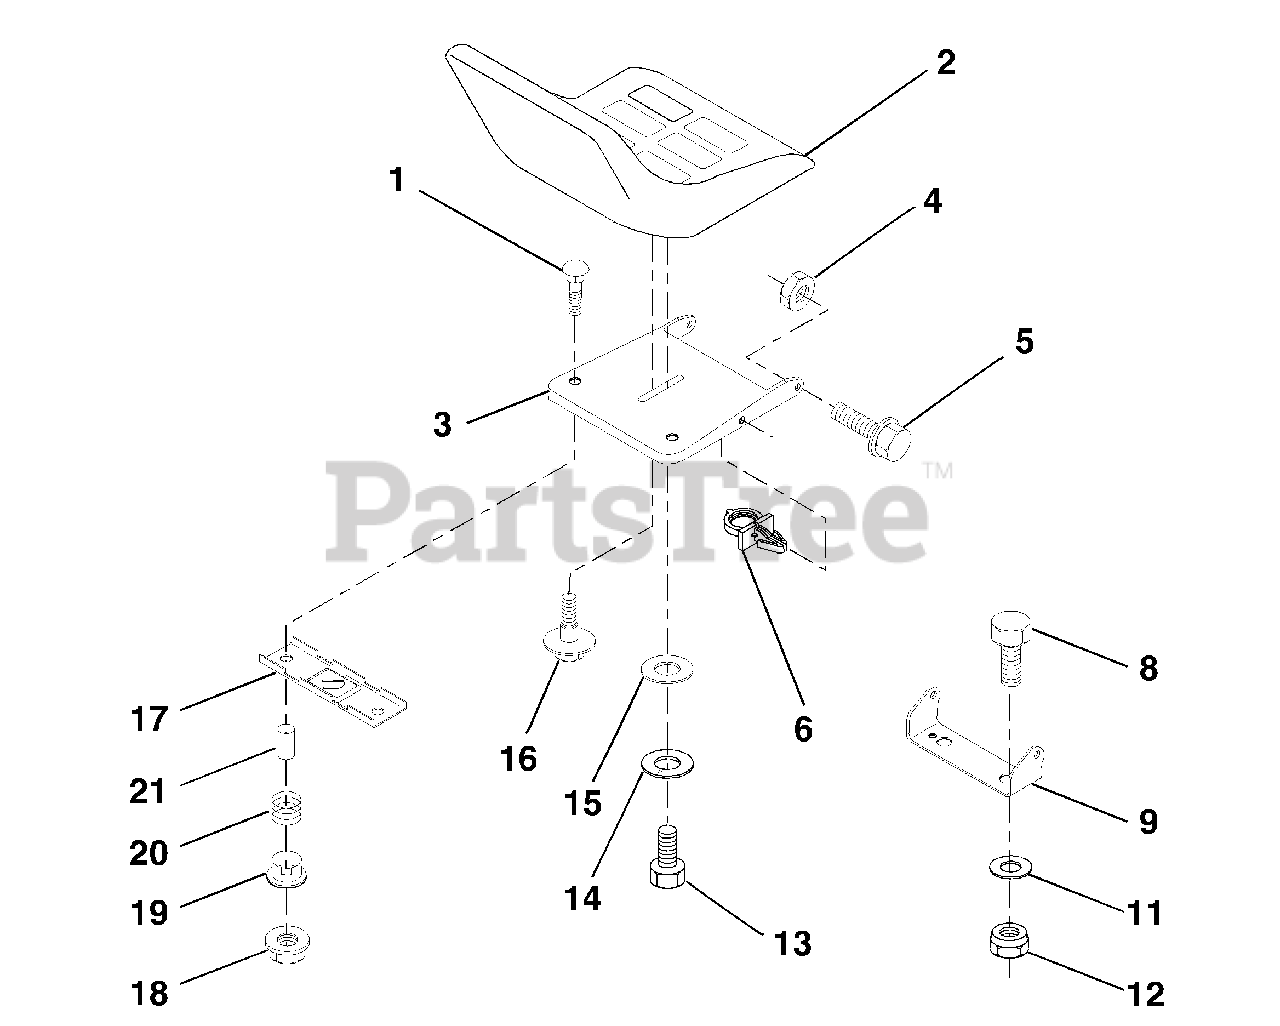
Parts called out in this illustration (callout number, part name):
1	Bolt, Carriage 1/4-20 x 1-1/2
2	Seat
3	Pan, Seat
4	Nut, Lock Hex w/Ins. 5/16-18
5	Bolt, Shoulder 5/16-18 UNC
6	Clip, Insulated
8	Bolt, Fin Hex 3/8-16 UNC x 1
9	Bracket, Pivot Seat
11	Washer 12/32 x 2 x 10 Ga.
12	Nut, Lock Hex w/Wsh 3/8-16
13	Bolt, Hex 1/2-13 x 7/8
14	Washer, Lock Hvy. Hlicl Spring 1/2
15	Washer, 17/32 x 1-3/16 x 12 Ga.
16	Bolt, Shoulder
17	Bracket, Switch, Mounting
18	Nut, Hex Large Flange Lock
19	Bushing, Snap
20	Spring, Compression
21	Spacer, Split 28 Id. x .88 Lg.
